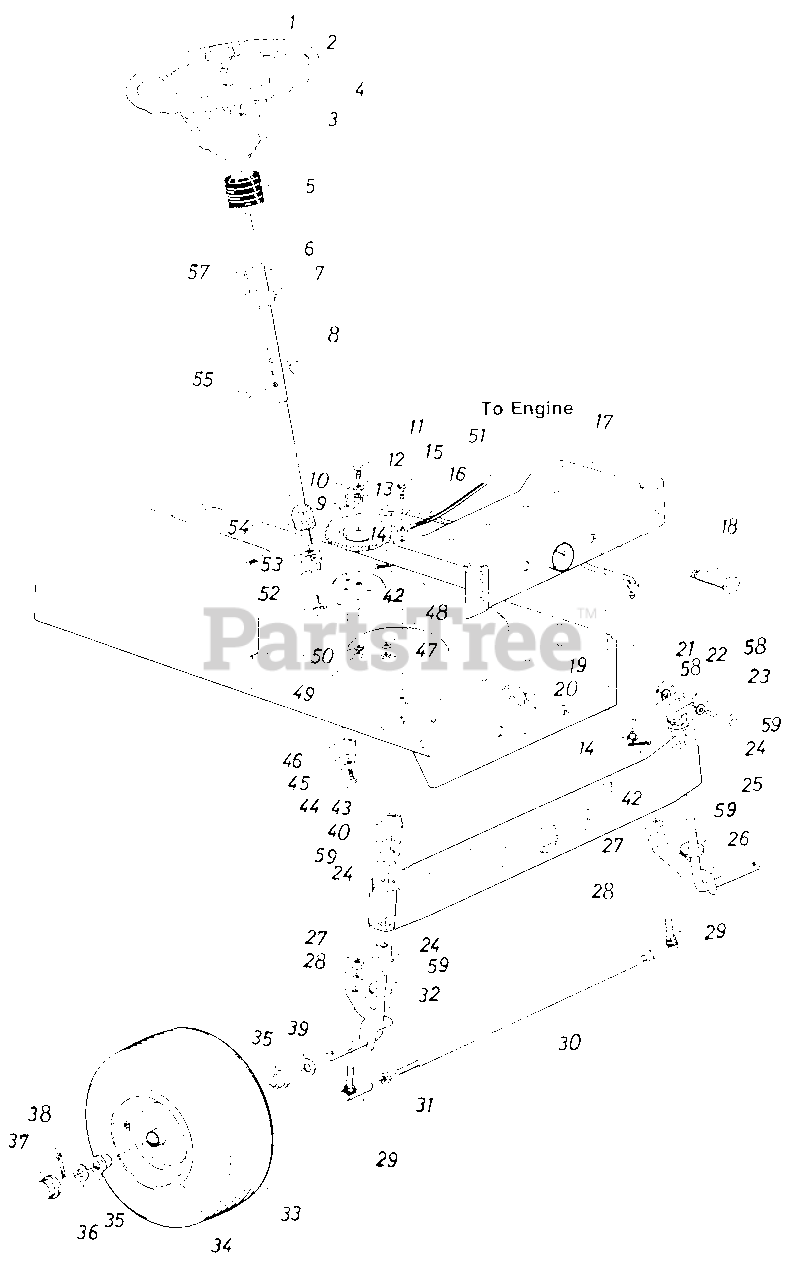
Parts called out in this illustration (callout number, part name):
1	Steering Wheel Cap
2	Hex Nut 5/16-18 Thd.
3	Belleville Wash. .345" I.D.
4	Steering Wheel 12" Dia.
5	Steering Bellow-4.5"
6	Steering Column Ass'y.
7	Flange Bearing .890 I.D. x 1.36 O.D.
8	Internal Cotter Pin 1/4" Dia.
9	Fl-Wash. .438" I.D. x 1.37"O.D.
10	Shoulder Bolt .437" Dia. x .35 Lg. 5/16-18 Thd.
11	Hex Bolt 3/8-24 x 1.0" Lg. (Grade 5)
12	Fl-Wash. .38" I.D. x 1.0" O.D.
13	Spacer.380" I.D. x .625" O.D. x .227
14	Flat Washer .56 I.D. x 1.0 O.D.
15	Hex Wash. Hd. Self-Tap Scr.
16	Steering Drag Link
17	Front Pivot Brkt.
18	Shoulder Bolt .498" Dia. x 2.04 Lg. 3/8-16 Thd.
19	Hex Nut 3/8-16 Thd.
20	L-Wash. 3/8" I.D.
21	Hex Cent. L-Nut 5/16-24 Thd.
22	Steering Arm Front Axle
23	Hex Bolt 5/16-24 x 2.00" Lg. (Grade 5)
24	Hex Flg. Brg. .634 I.D.
26	Front Axle Ass'y.-L.H.
27	Hex Nut 3/8-24 Thd.
28	L-Wash. 3/8" I.D.
29	Ball Joint 3/8-24 Thd.
30	Tie Rod
31	Hex Jam Nut 3/8-24 Thd.
32	Front AxIe Ass'y.-R.H.
33	Wheel Ass'y. Comp.
34	Front Wheel Rim Only
35	Bearing
36	Fl-Wash. .635 I.D. x 1.59" O.D.
37	Front Wheel Hub Cap
38	Cotter Pin 1/8" Dia. x 1.25" Lg.
39	Fl-Wash. .635" I.D. x 1.20" O.D.
40	Push Cap 5/8" Dia. Rod
42	Cotter Pin 1/8" Dia. x 1.0" Lg.
43	Hex L-Bolt 5/16-18 x .62" Lg.
44	L-Wash. 5/16" I.D.
45	Fl-Wash. .344" I.D. x 1.25" O.D.
46	Spacer (Plastic)
47	Hex Nut 3/8-24 Thd.
48	L-Wash. 3/8" I.D.
49	Hex Nut 5/16-18 Thd.
50	L-Wash. 5/16" I.D.
51	Steering Gear Segment
52	Hex Flg. Brg. .634 I.D.
53	Fl-Wash. (Hardened)
54	Steering Shaft Lower
55	Clevis Pin 1/4" Dia. x 1.00" Lg.
57	Oval Hd. Cr.-Sunk Scr. #10 x 518" Lg.
58	Bell-Wash.
59	Fl-Wash. (Hardened)
